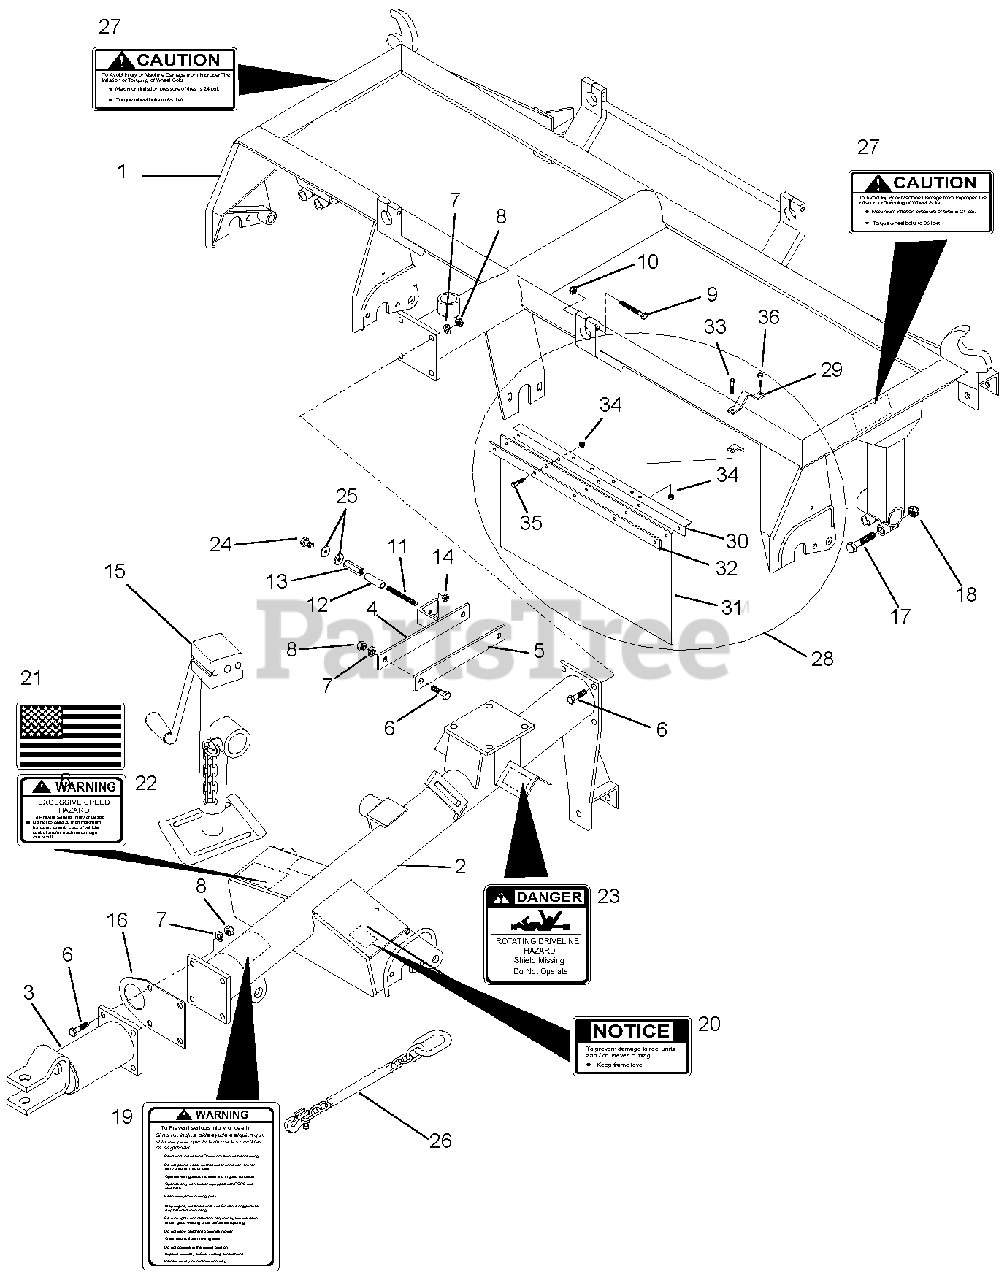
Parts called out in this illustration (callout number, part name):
1	Weldment, Mainframe
2	Tongue Assembly
3	Weldment, Clevis Hitch
4	Weldment, Tongue Brace
5	Brace, Tongue Left Hand
6	Cap Screw, .50-13 x 1.5 Hex 5
7	Washer, Lock .50
8	Nut, Hex .50
9	Cap Screw, .375-16 x 3 Hex 5
10	Nut, .375-16 Hex
11	Stud, Belt Guard
13	Nut, .375-16 Hex Coupler
14	Nut .375-16 Hex CP Nylock
15	Jack, Screw 5000 lb.
16	Holder, Hydraulic Hose
17	Cap Screw, .50-13 x 2.5 Hex 5
18	Nut, .50-13 Hex Nylock
19	Decal, Warning
20	Decal, Notice
21	Decal, US Flag
22	Decal, Warning
23	Decal, Danger
24	Cap Screw, .375-16 x .75 Hex 5
25	Washer, Flat .375
26	Chain, Safety Tow
27	Decal, Caution
28	Deflector Assembly (Includes items 29-36)
29	Clamp, Deflector
30	Mounting Angle
31	Deflector
32	Clamp Bar
33	Cap Screw, 5/16-18 x 1-1/2 Hex 5
34	Nut, Hex Nyloc 5/16-18
35	Cap Screw, 5/16-18 x 1 Hex
36	Cap Screw, 5/16-18 x 1-1/4 Hex
